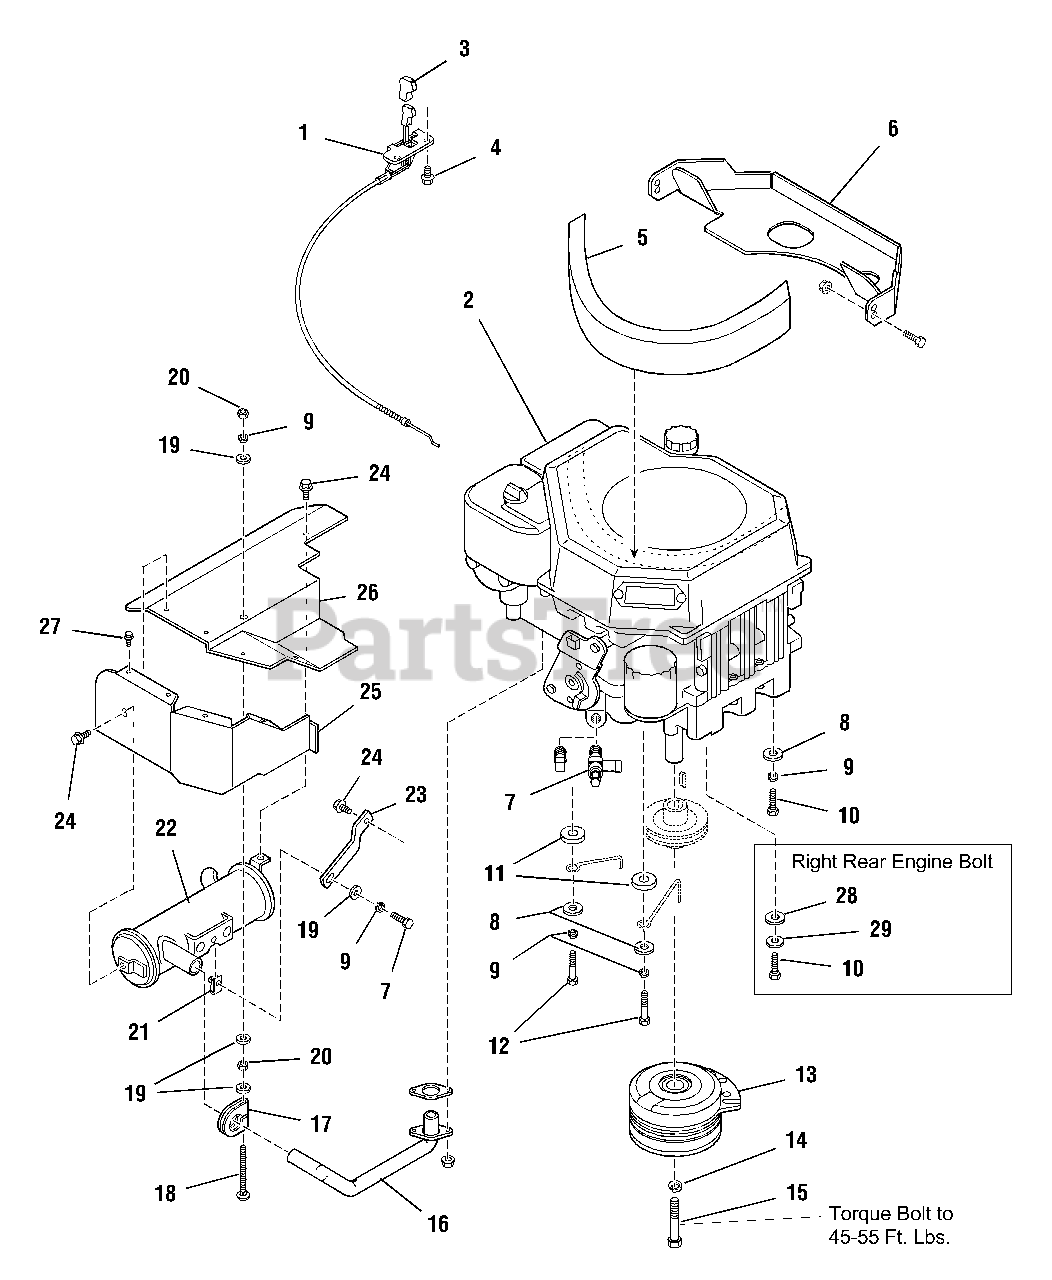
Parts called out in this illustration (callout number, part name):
1	THROTTLE CONTROL ASSEMBLY
2	ENGINE ASSEMBLY, 14 HP Kohler
2	ENGINE ASSEMBLY, 16 HP Kohler
3	KNOB, Throttle
4	SCREW, Plastite, 1/4-10 x 1/2
5	SEAL, Air Inlet
7	VALVE, Shut Off
8	WASHER, Plain, 5/16
9	LOCKWASHER, 5/16
10	SCREW, Hex, M08 - 1.25 x 30mm
11	WASHER, Plain
12	CAPSCREW, Hex Hd., M08 - 1.25 x 40mm
13	CLUTCH, Electric
14	LOCKWASHER, 7/16
15	CAPSCREW, Hex, 7/16-20 x 3-1/4
16	PIPE, Exhaust
17	CLAMP, Muffler
18	CARRIAGE BOLT, 5/16-18 x 3-1/4
19	WASHER, 5/16
20	NUT, Hex, 5/16-18
21	NUT, Speed, 5/16-18
22	MUFFLER ASSEM.
23	SUPPORT, Muffler
24	SCREW, Hex, Taptite, 5/16-18 x 1/2
25	AIR DUCT, Bottom
26	SHIELD, Muffler
27	SCREW, Hex, Thd. Form, #10-16 x 3/8
28	WASHER, Plain, 5/16
29	LOCKWASHER, Internal Tooth, 5/16
